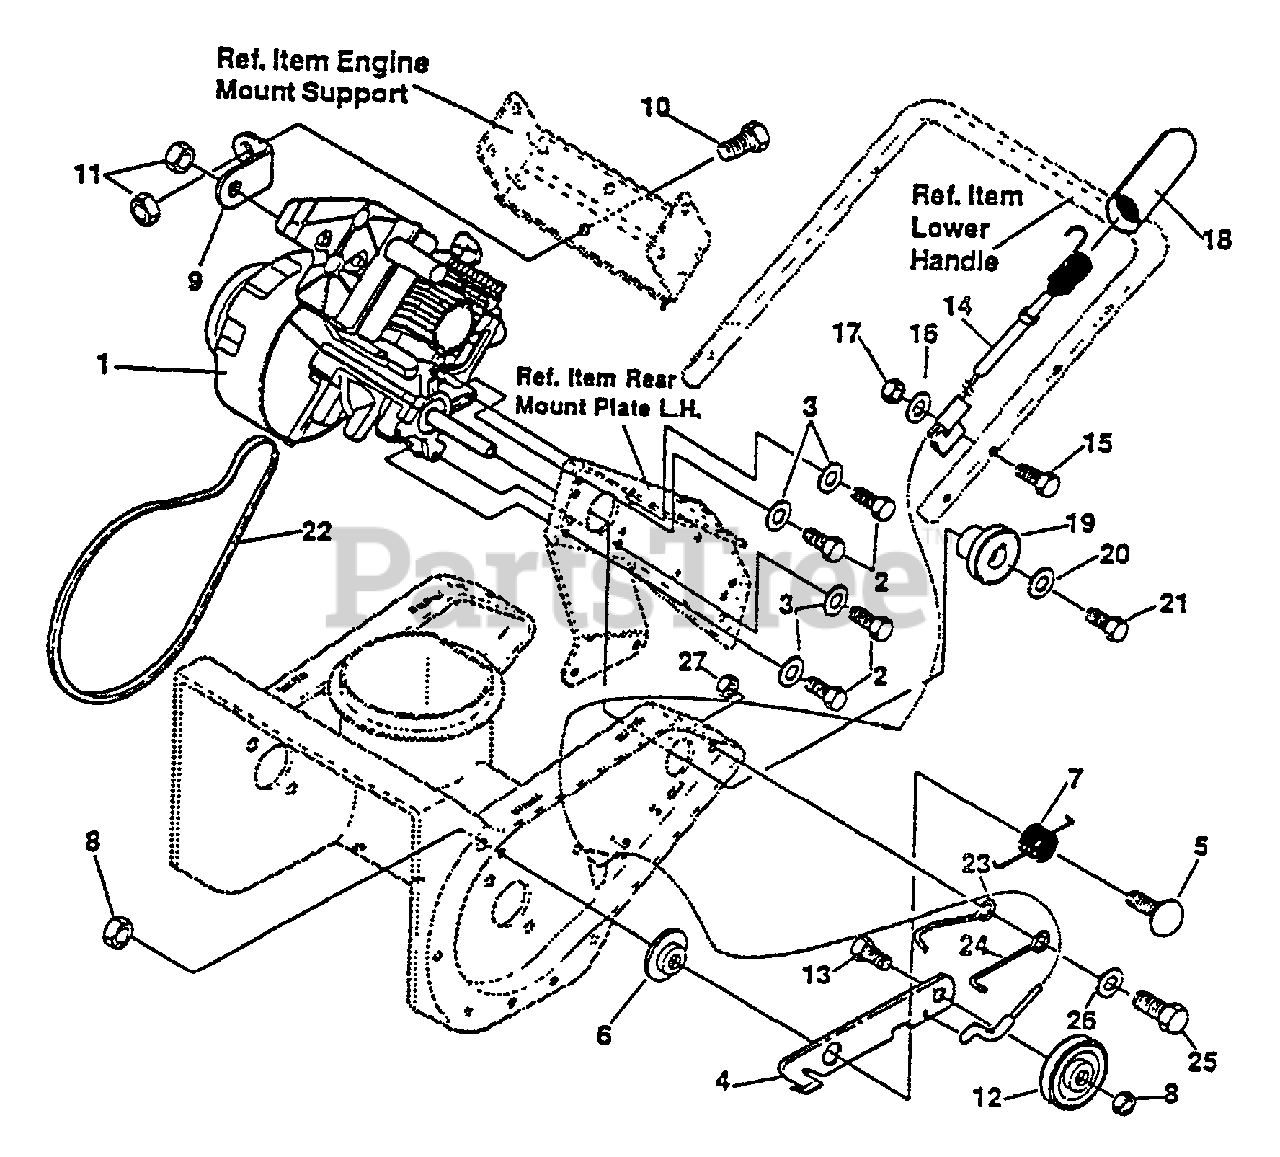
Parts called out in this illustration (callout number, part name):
2	SCREW
3	WASHER
4	BRACKET, IDLER ARM
5	BOLT, IDLER ARM
6	SPACER
7	SPRING
8	LOCKNUT - 3/8-16
9	SUPPORT, ENGINE
10	SCREW - 5/16-18 X0.50" -- HEX HEAD CAP
11	NUT, 5/16"-18
12	IDLER PULLEY, 1.88×0.5×0.38
13	BOLT 3/8"-16×1.25 SPCARR
14	CABLE, DRIVE CONTROL
15	SCREW
16	WASHER
17	NUT, 1/4"-20
19	PULLEY HALF, 3L, 2.00
20	WASHER
21	SCREW - 5/16-24×0.88
22	BELT, V3LX35, 0.048 D
23	GUIDE, BELT 0.381DX2.66
24	GUIDE, BELT 0.381DX3.30 OFF
25	SCREW
26	WASHER
27	NUT, 3/8"-16
